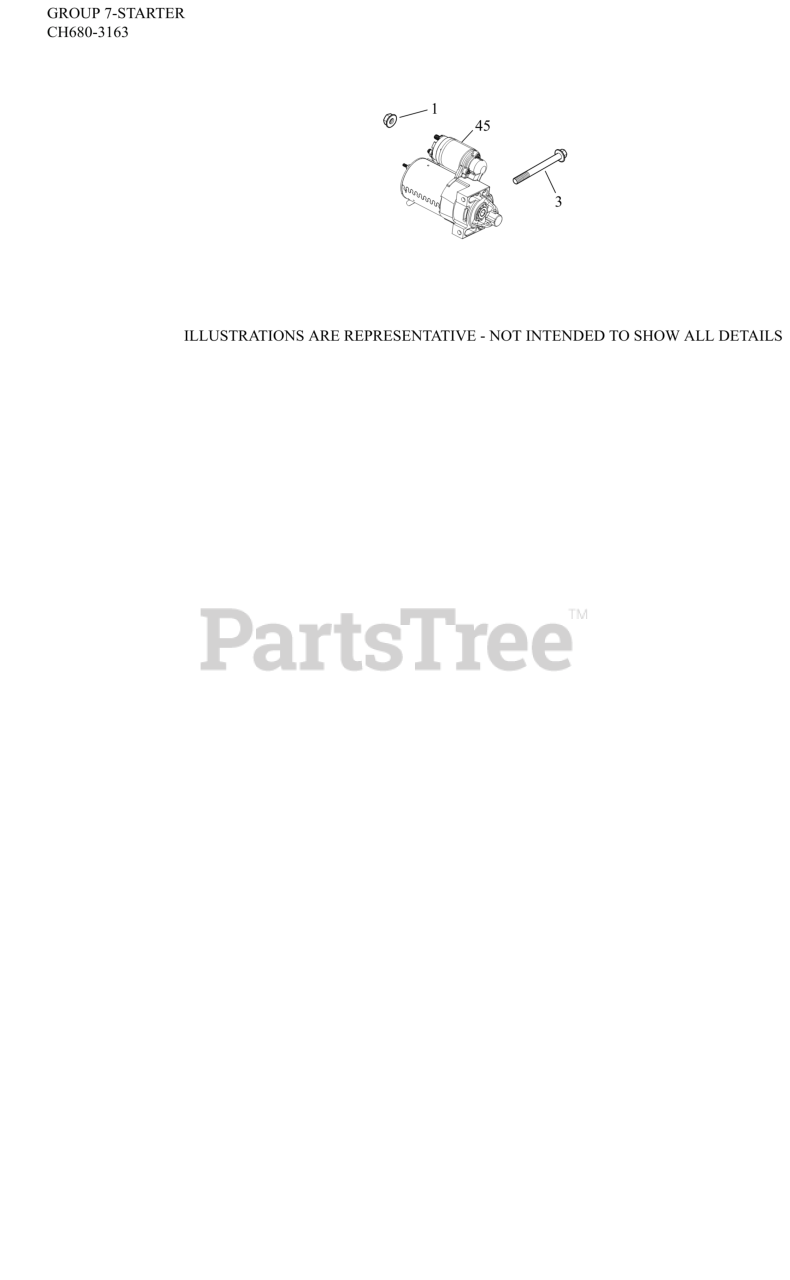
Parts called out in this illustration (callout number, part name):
1	NUT, FLG M8X1.25
3	SCREW, FLG M8X1.25X80
45	STARTER, SOLENOID SHIFT
